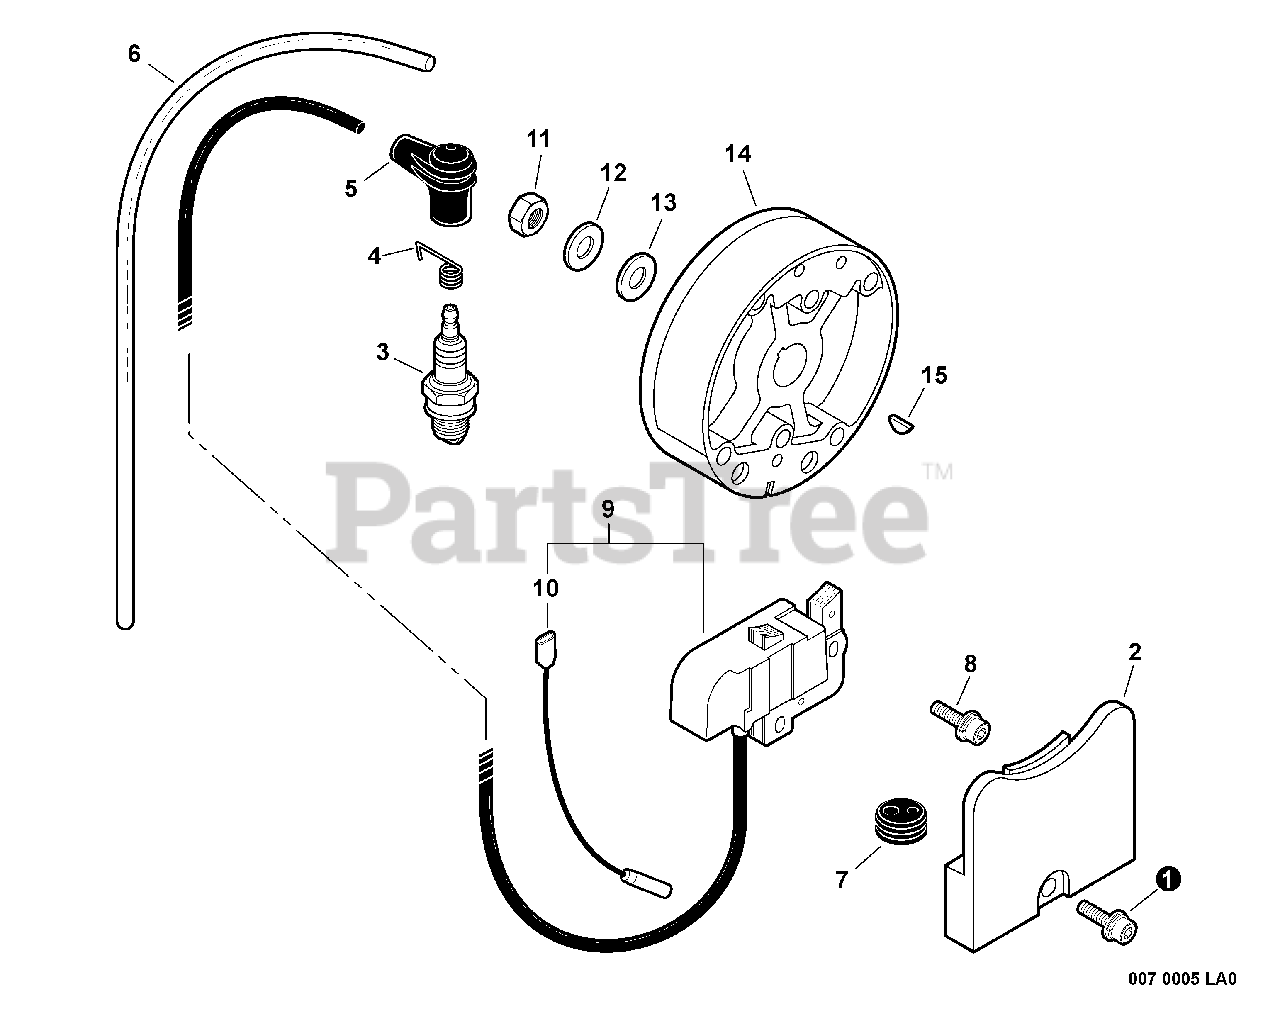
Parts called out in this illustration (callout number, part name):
1	SCREW - 5X22
2	COVER, DUST
3	SPARK PLUG -- BPM-8Y
4	TERMINAL, SPARK PLUG CAP
5	CAP, SPARK PLUG
6	TUBE - VINYL
8	SCREW - 5X22
9	IGNITION COIL KIT
10	LEAD - IGNITION
11	NUT - 10
12	LOCKWASHER - 10
13	WASHER - 10
14	FLYWHEEL
15	KEY - 3X14
